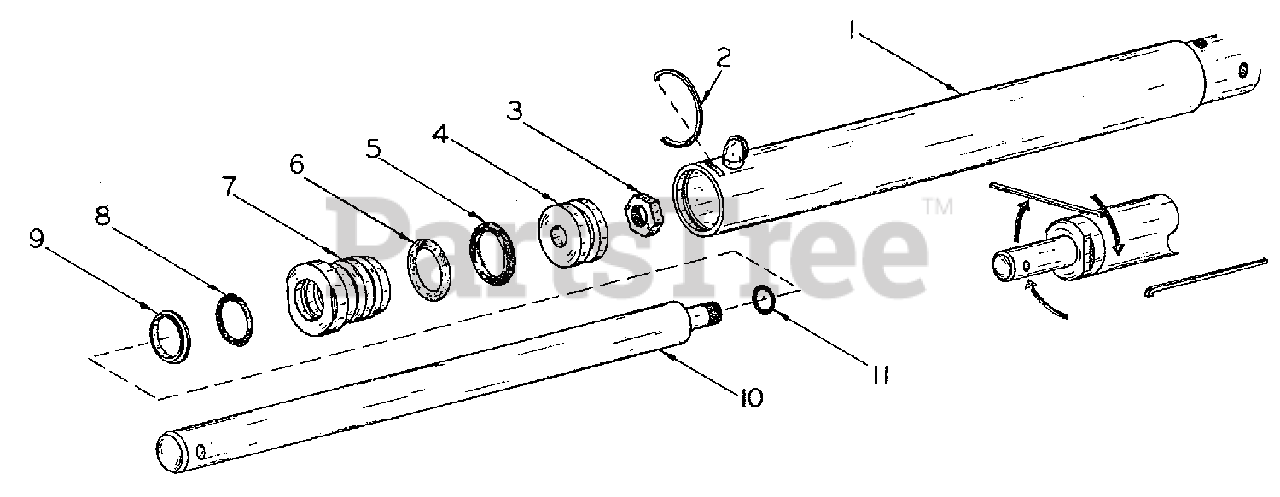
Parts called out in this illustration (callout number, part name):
1	BARREL ASSEMBLY (Lift)
1	BARREL ASSEMBLY (Dump)
2	WIRE, Locking
3	NUT, Piston
5	SEAL, O-Ring, Piston
6	O-RING, Head
8	SEAL, O-Ring, Head
9	SHAFT, Seal
10	SHAFT (Lift)
10	SHAFT (Dump)
11	GASKET, Piston
